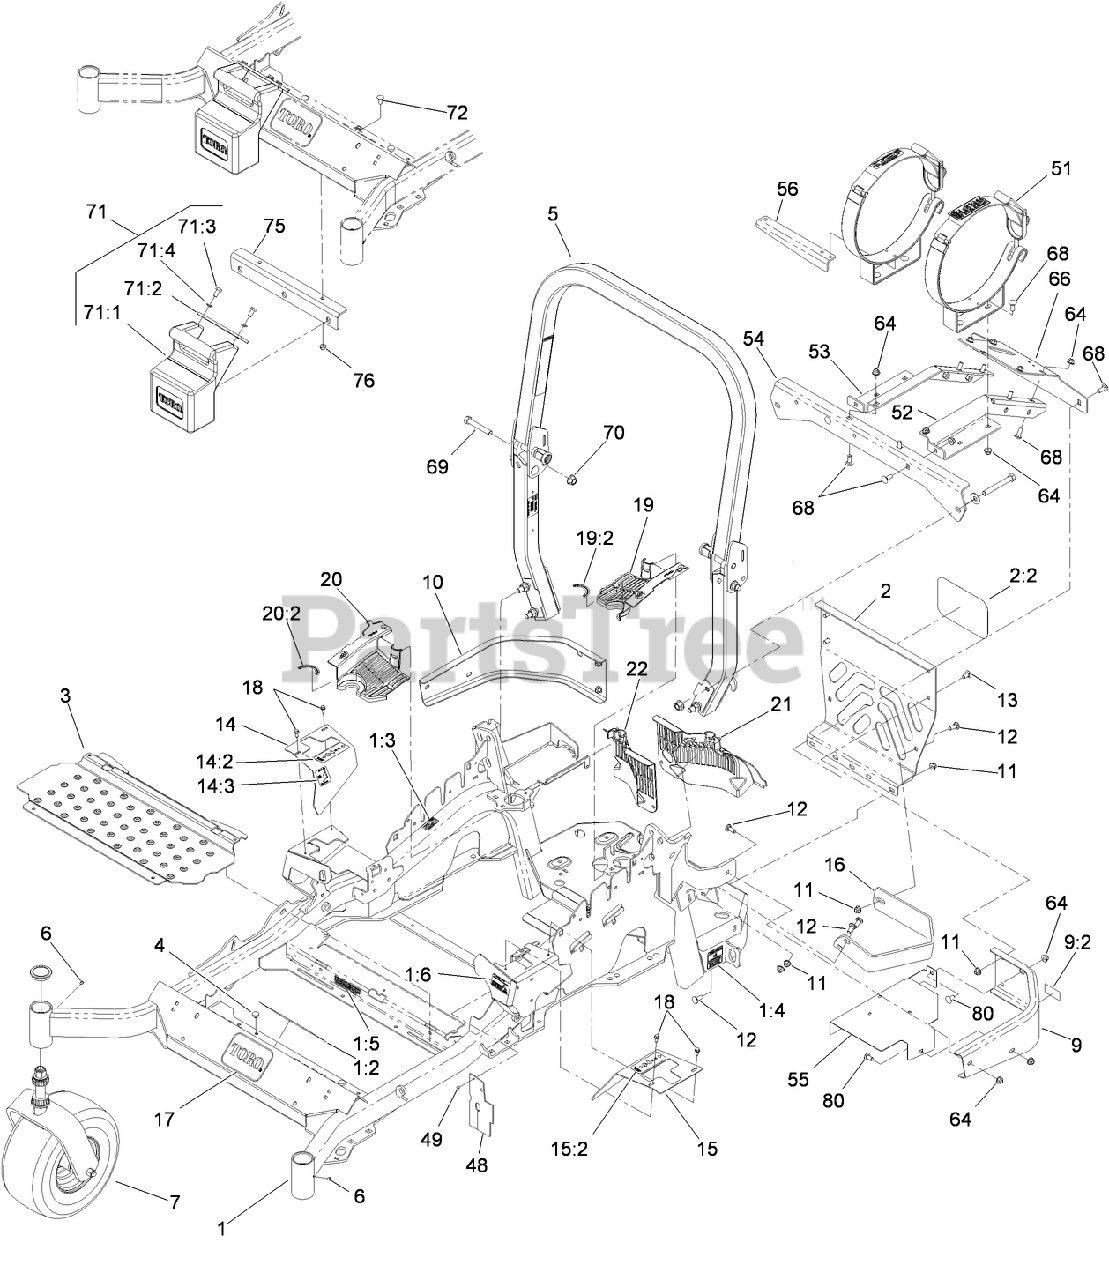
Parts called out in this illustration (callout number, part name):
1	MAIN FRAME ASM
1:2	DECAL-CAUTION
1:3	DECAL-SLOPE
1:4	DECAL-BELT DRIVE
1:5	DECAL-ARRESTER, SPARK
1:6	DECAL-FUEL FILL
2	REAR GUARD ASM
2:2	DECAL
3	FLOORPAN
4	BUMPER
5	ROPS ASM
7	Caster Wheel ASM
9	LH BUMPER ASM
9:2	DECAL-CAUTION
10	BUMPER-RH
11	NUT-HF, NI
12	SCREW-CARR
13	SCREW-CARR
14	RH MOTION CONTROL COVER ASM
14:2	DECAL-MOTION CONTROL
14:3	DECAL-PARK BRAKE
15	LH MOTION CONTROL COVER ASM
15:2	DECAL-MOTION CONTROL
16	GUARD-MUFFLER
17	DECAL
18	SCREW-HWH
19	LH HYDRO GUARD ASM
19:2	DECAL-HYDRO OIL
20	RH HYDRO GUARD ASM
20:2	DECAL-HYDRO OIL
21	GUARD-HYDRO, REAR (LH)
22	GUARD-HYDRO, REAR (RH)
48	DEFLECTOR-AIR FLOW
49	RIVET-POP
51	TANK BRACKET ASM (SET)
52	LH LPG FRAME ASM
53	RH LPG FRAME ASM
54	SUPPORT-LPG FRAME, FRONT
55	BRACKET-AIR, LPG CLEANER
56	PLATE-INDEX, LPG TANK
64	NUT-HF, NI
66	SUPPORT-REAR FRAME, LPG
68	BOLT-CARR
69	SCREW-HH
70	NUT-LOCK
71	WEIGHT ASM
71:1	WEIGHT-43 LB
71:2	TAB-SUPPORT, WEIGHT
71:3	SCREW-HH
71:4	WASHER-LOCK
72	SCREW-CARR
75	BRACKET-MOUNT, WEIGHT
76	NUT-HF, NI
80	SCREW-CARR
